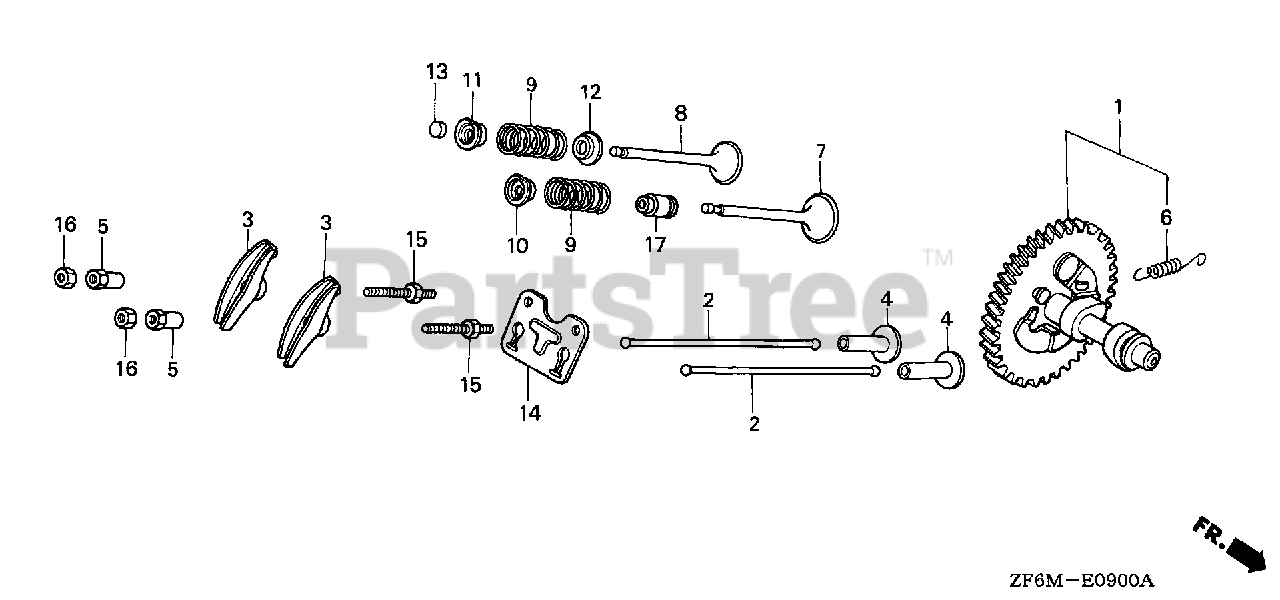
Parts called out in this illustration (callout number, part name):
1	CAMSHAFT ASSY.
2	ROD, PUSH
3	ARM, VALVE ROCKER
4	LIFTER, VALVE
5	PIVOT, ROCKER ARM
6	SPRING, WEIGHT RETURN
7	VALVE, IN.
8	VALVE, EX.
9	SPRING, VALVE
10	RETAINER, IN. VALVE SPRING
11	RETAINER, EX. VALVE SPRING
12	SEAT, VALVE SPRING
13	ROTATOR, VALVE
14	PLATE, PUSH ROD GUIDE
15	BOLT, PIVOT (8MM)
16	NUT, PIVOT ADJ.
17	SEAL, VALVE STEM
